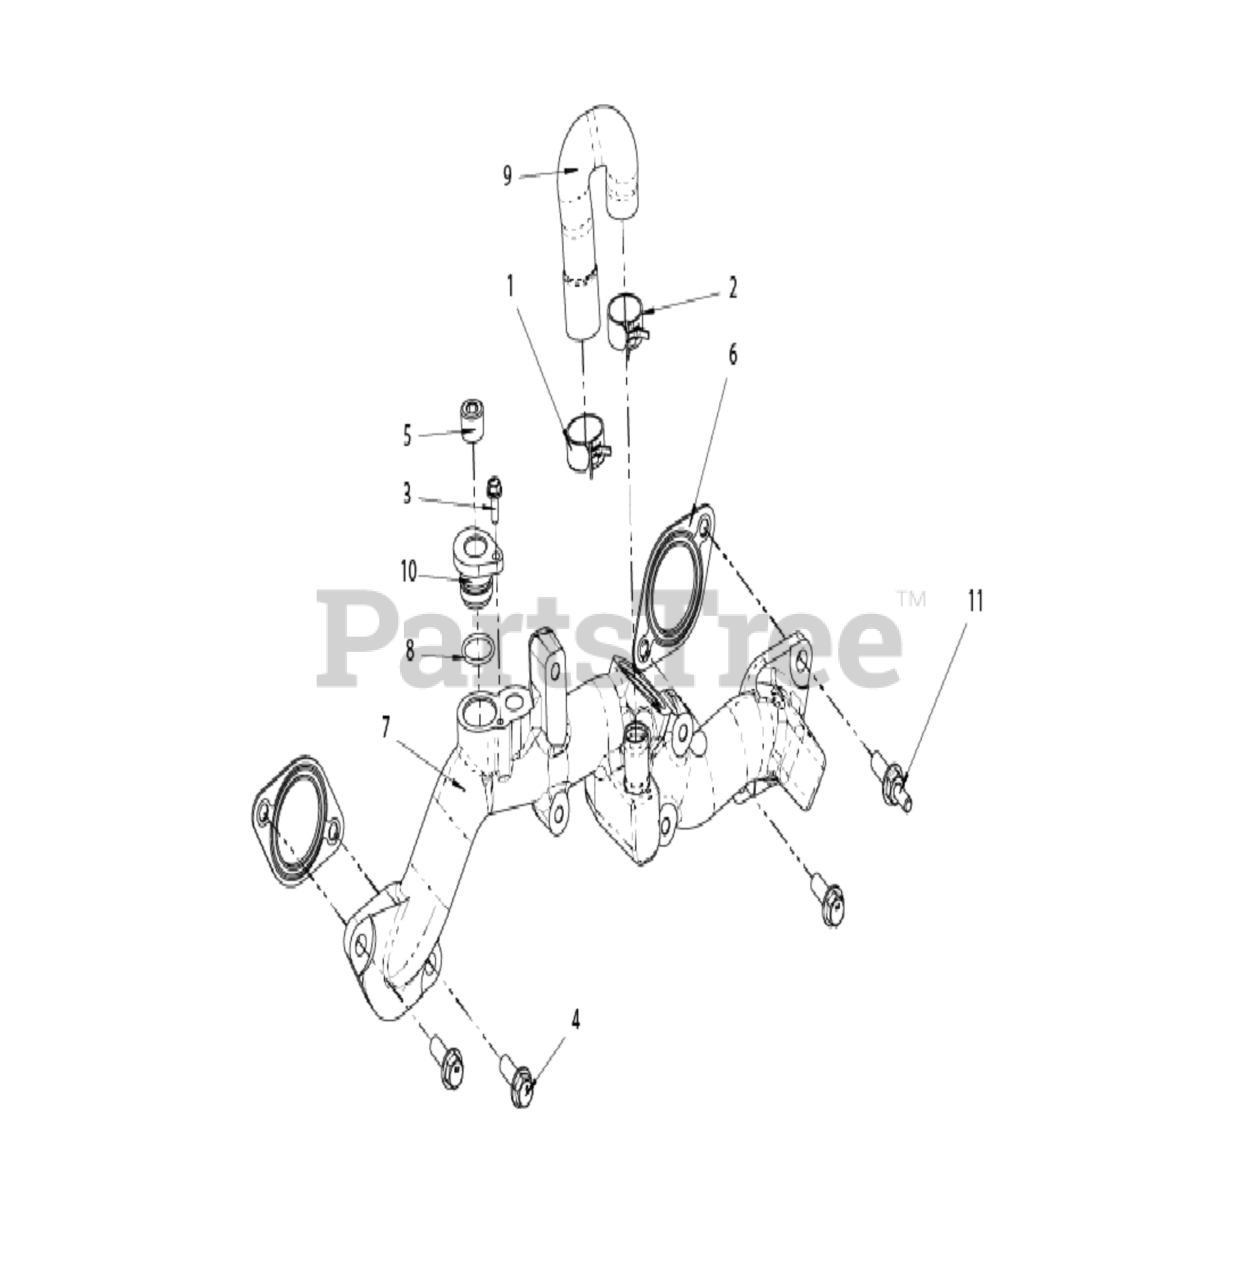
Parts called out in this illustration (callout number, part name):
1	*CLAMP
2	*CLAMP
3	*BOLT
4	*FASTENER, Pipe
5	*STEEL PLUG
6	*GASKET
7	*PIPE ASSEMBLY, Crossover
8	*O-RING
9	*HOSE
10	*FITTING
11	*STUD
